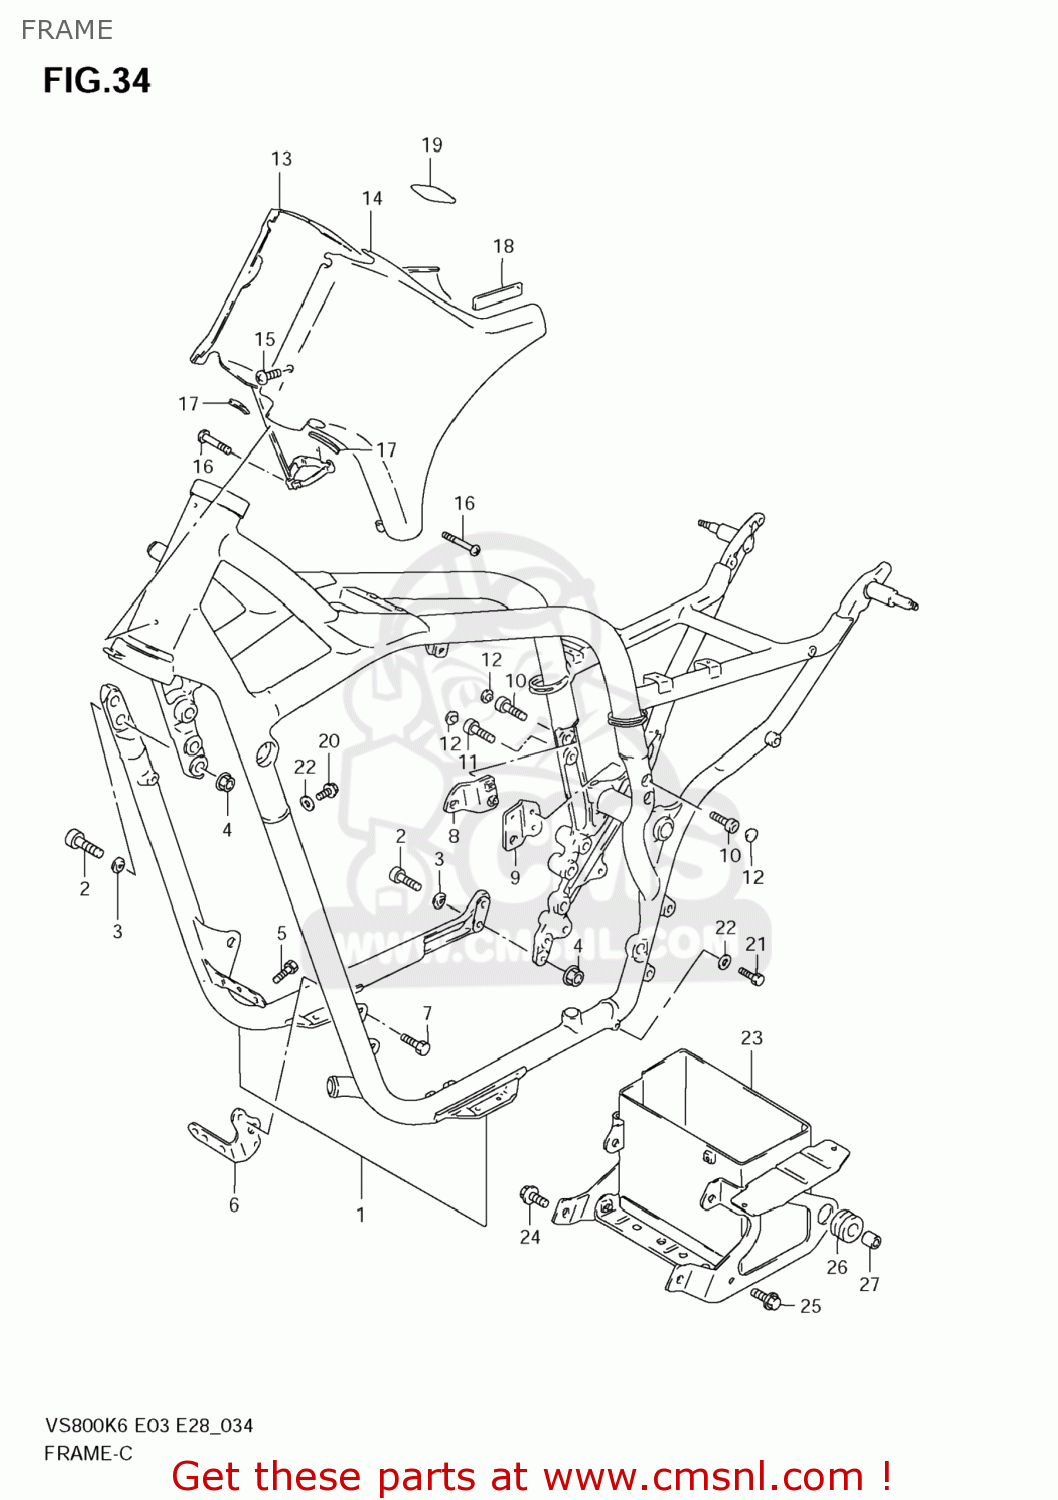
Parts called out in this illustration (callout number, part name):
1	FRAME SET(SILVER)
2	BOLT(10X33)
3	WASHER
4	NUT
5	BOLT
6	PLATE,ENGINE MOUNT NO.1,L
7	BOLT
8	PLATE,ENGINE MOUNT NO.3,R
9	PLATE,ENGINE MOUNT NO.3,L
10	BOLT(8X30)
11	BOLT
12	CAP(OD:14.5)
13	COVER,FRAME HEAD,R(SILVER)
14	COVER,FRAME HEAD,L(SILVER)
15	SCREW(6X10)
16	SCREW
17	MOLDING
18	PROTECTOR(20X90)X2
19	TAPE,FRAME HEAD COVER
20	UNION BOLT,AIR VENT
21	BOLT
22	GASKET(6.4X11.5X0.8) (NAS)
23	HOLDER,BATTERY
24	BOLT
25	BOLT
26	CUSHION
27	BUSH
